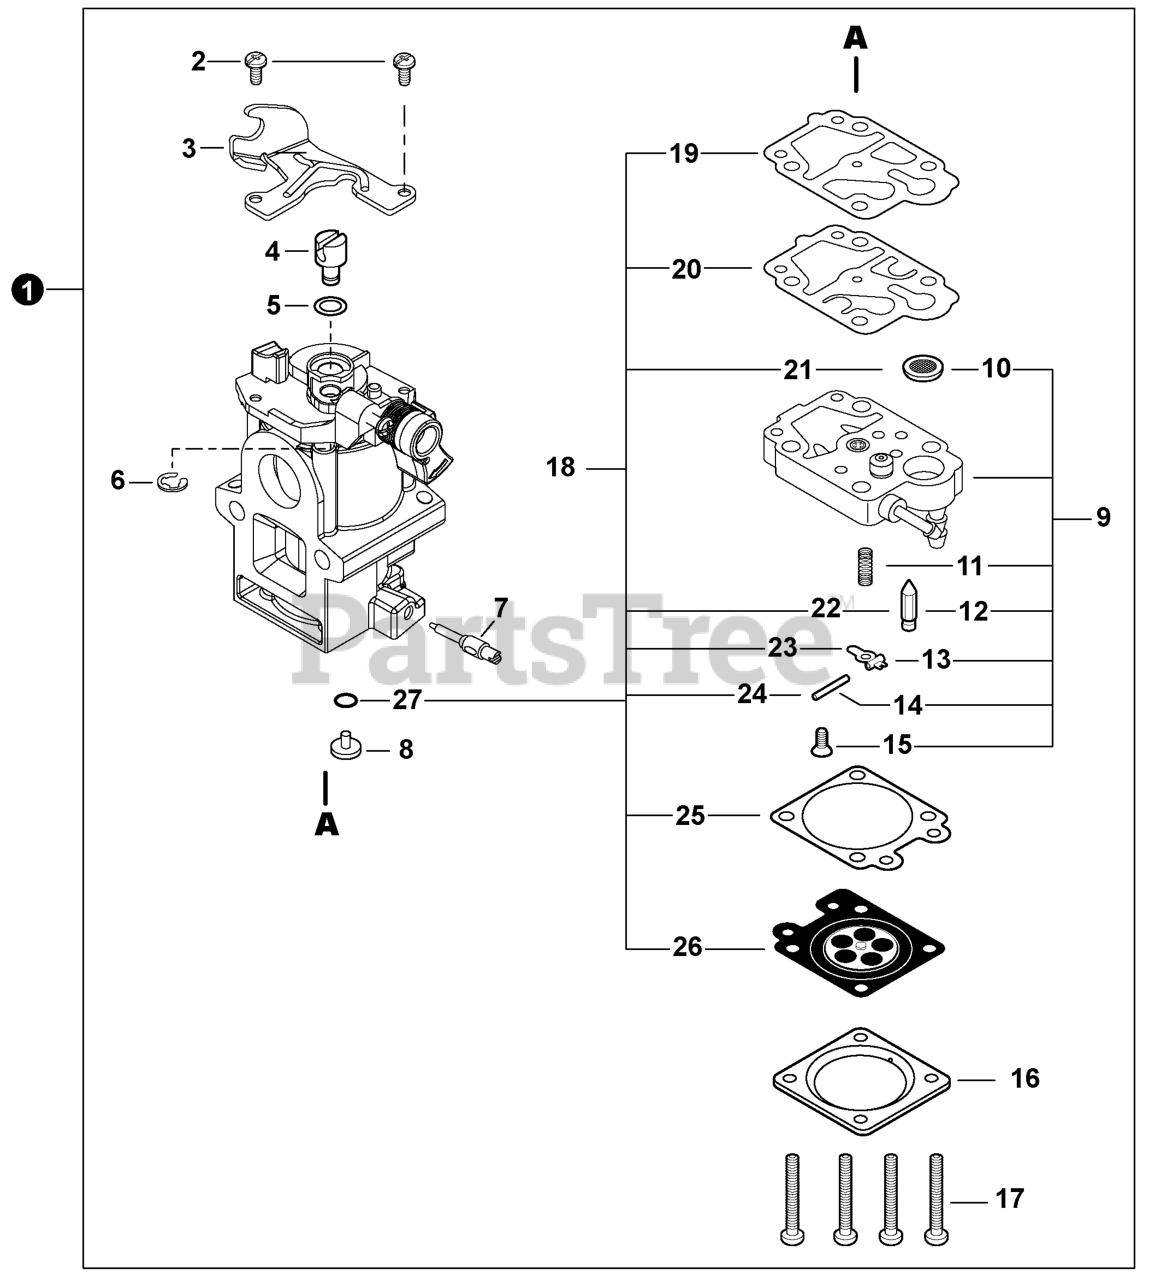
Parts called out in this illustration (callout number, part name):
1	CARBURETOR WYAB-2
3	BRACKET, THROTTLE CABLE
7	NEEDLE, MIXTURE
9	BODY ASSY, PUMP
10	SCREEN, FUEL INLET
11	SPRING, METERING LEVER
12	VALVE, INLET NEEDLE
13	LEVER, METERING
14	PIN, METERING LEVER
15	SCREW
16	COVER, METERING DIAPHRAGM
18	REPAIR KIT, CARBURETOR
19	GASKET, PUMP
20	DIAPHRAGM, FUEL PUMP
21	SCREEN, FUEL INLET
22	VALVE, INLET NEEDLE
23	LEVER, METERING
24	PIN, METERING LEVER
25	GASKET, METERING DIAPHRAGM
26	DIAPHRAGM, METERING
27	O-RING
